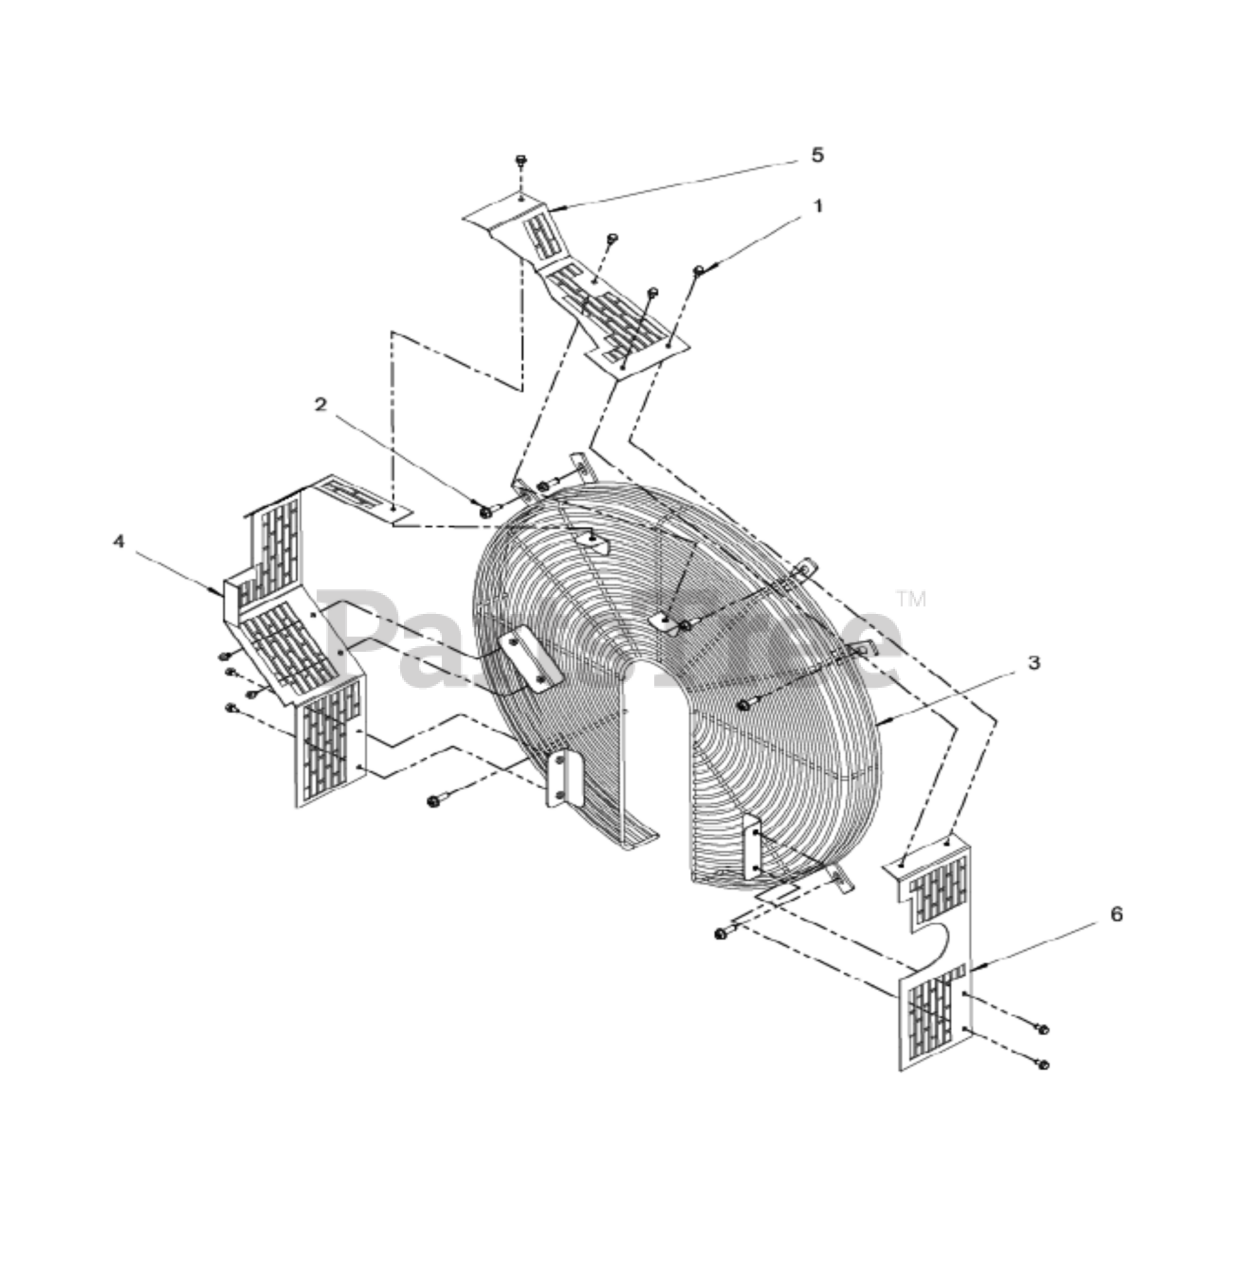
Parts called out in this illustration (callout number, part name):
1	*BOLT
2	*BOLT
3	*GUARD, Fan
4	*GUARD, Fan
5	*GUARD, Belt
6	*GUARD, Belt
